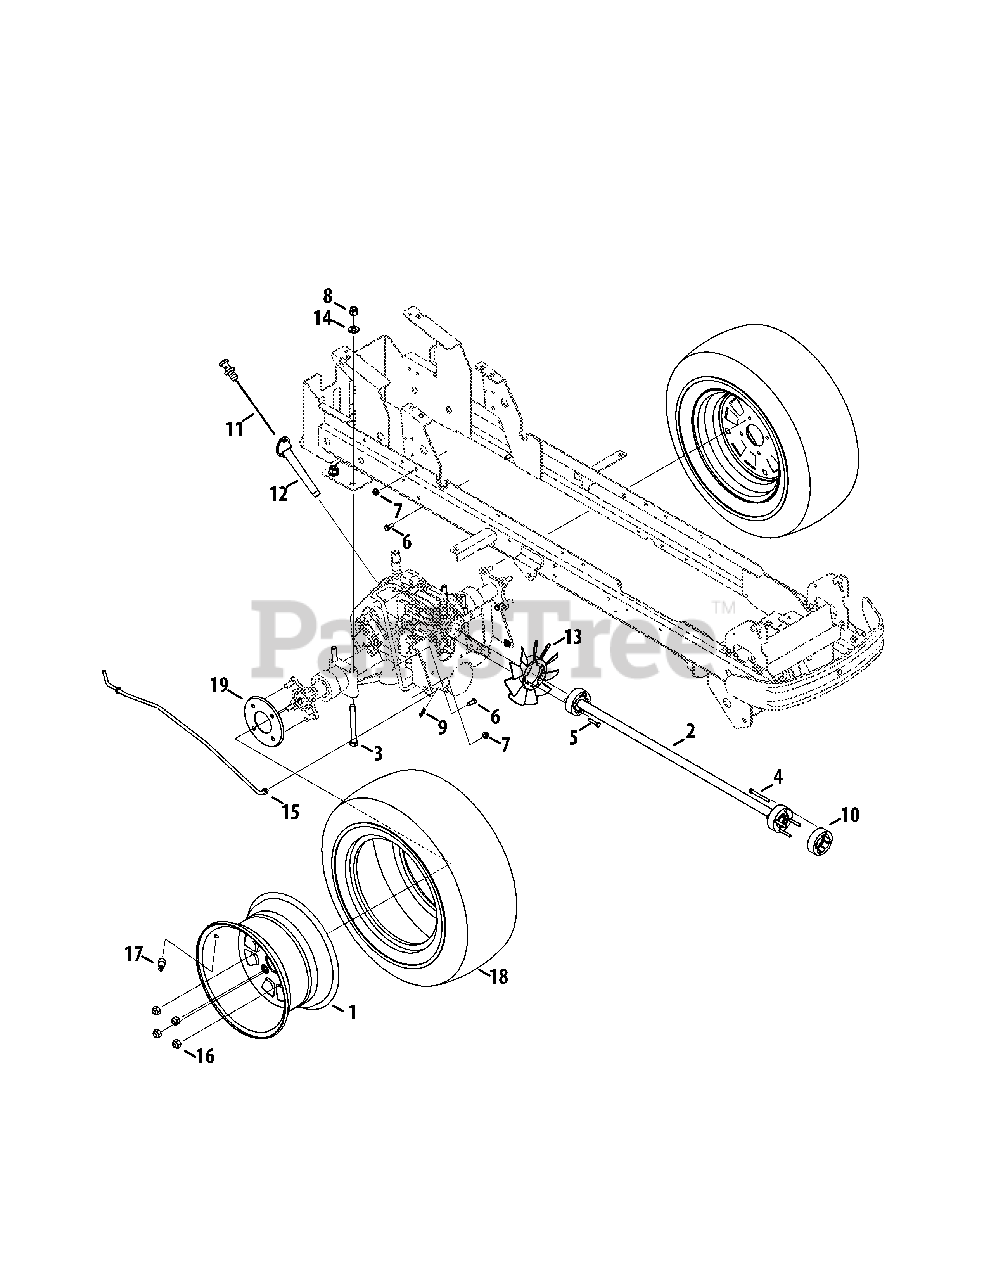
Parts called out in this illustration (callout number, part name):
2	Shaft Assembly, 30.55
3	Hex Screw, 1/2-20 x 4.50
4	Hex Screw, 1/4-20 x 2.50
5	Hex Screw, 1/4-20 x 1.25
6	Hex Screw, 5/16-18 x .75
7	Flange Lock Nut, 5/16-18
8	Hex Lock Nut, 1/2-20
9	Bow-Tie Cotter Pin, 72
10	Shaft Adapter, Basic
11	Transaxle Dipstick
12	Dipstick Holder
13	Pump Fan, 7.0
14	Flat Washer, .531 x 1.062 x .134
15	Hydro Relief Lever
16	Lug Nut, 7/16-14
17	Tubeless Air Valve
18	Tire, 23.0 x 10.5 x 12
